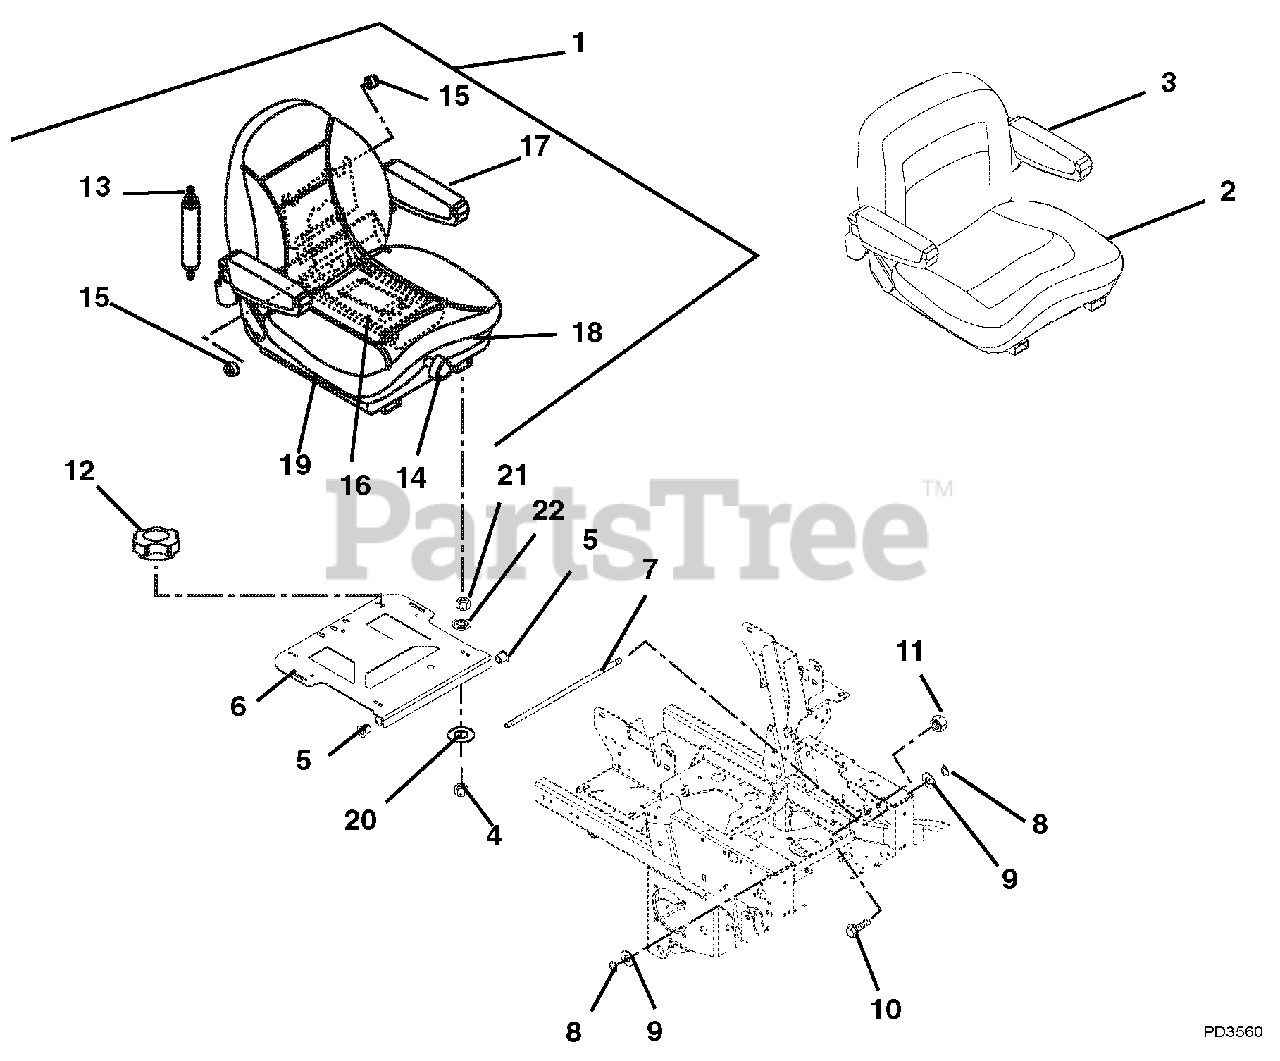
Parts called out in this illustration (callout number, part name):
1	Seat (991026, 027, 028, 031)
2	Seat (991029, 030, 032, 042)
3	Kit, Seat Arm Rests (991029, 030, 032, 042)
4	Nut, Locking Top Flange .31-18 (991029, 030, 032, 042)
5	Bushing, Flange .515 x .750 x .745 x 1.00
6	Seat Pivot Mount
7	Rod, Seat Frame Pivot
8	Ring, Retaining External .500 x .050
9	Washer, Thrust .531 x 1.00 x .063
10	Bolt, Shoulder EP .38-16 x .30 Hex
11	Nut, Locking-Center .38-16
12	Knob, Clamping .312-18 Nyloc
13	Kit, Damper w/Hardware (991026, 027, 028, 031)
14	Kit, Knob (1 per bag) (991026, 027, 028, 031)
15	Kit, Roller (4 per bag) (991026, 027, 028, 031)
16	Kit, Spring Cable (1 per bag) (991026, 027, 028, 031)
17	Kit, Arm Pad (1 per bag) (991026, 027, 028, 031)
18	Kit, Adjuster (1 per carton) (991026, 027, 028, 031)
19	Kit, Cushion (1 per carton) (991026, 027, 028, 031)
20	Washer, Flat-Steel .38 x .875 x .083 (991026, 027, 028, 031)
21	Bushing, Sleeve .377 x .624 x .235 (991026, 027, 028, 031)
22	Nut, Push .312 (991026, 027, 028, 031)
